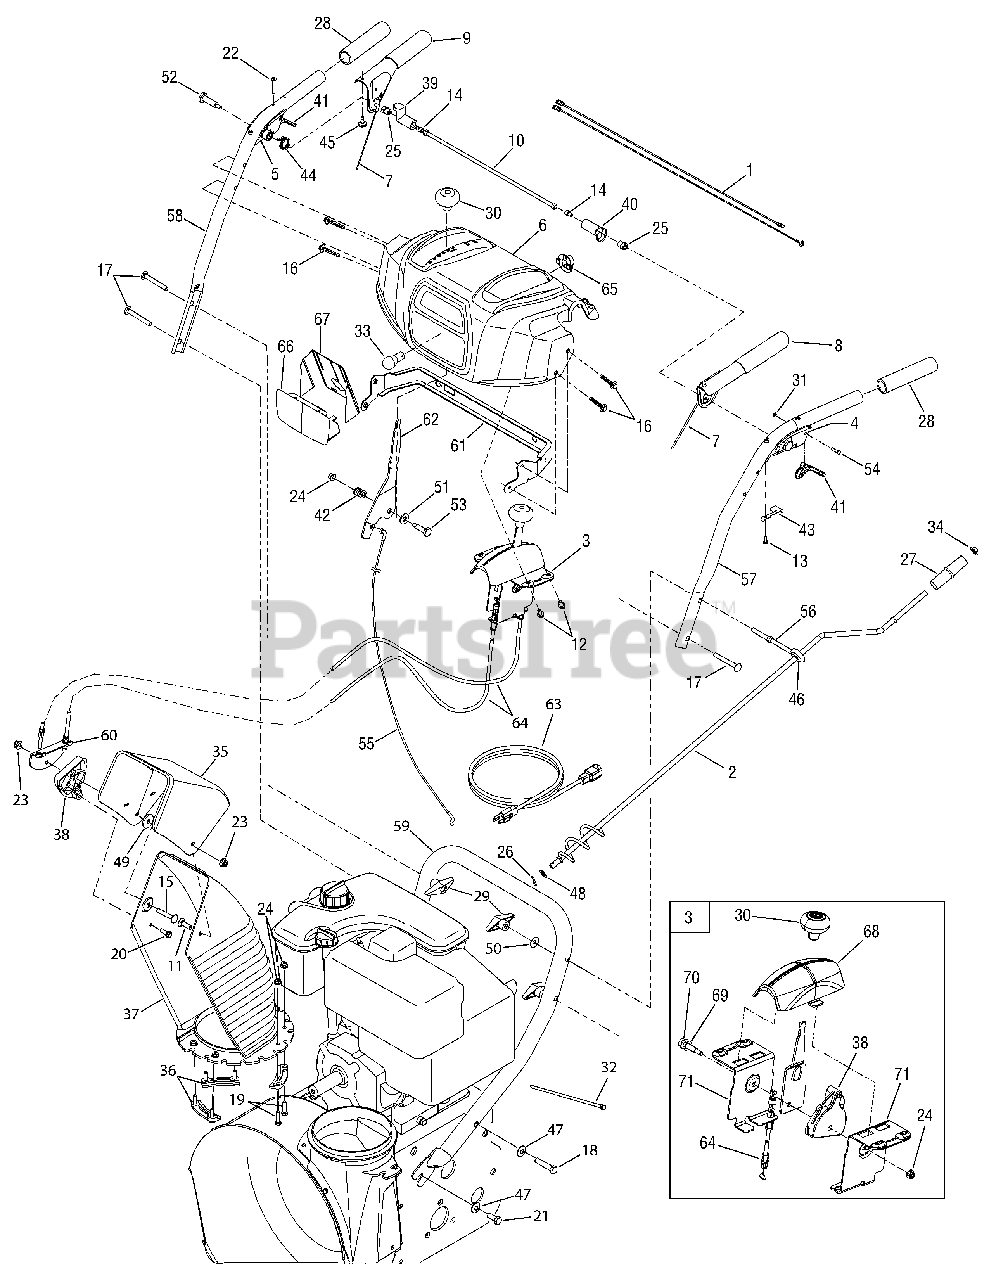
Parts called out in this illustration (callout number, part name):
1	Wire Harness
3	2-Way Chute Control (TM) Assy
4	Handle Clutch Lock - LH
5	Handle Clutch Lock - RH
6	Handle Panel
7	Cable Assembly, Auger/Drive
8	Handle Engage Assy - LH
9	Handle Engage Assy - RH
10	Rod Ass’y, Clutch Lock Pivot
11	Screw, Carriage, 5/16-18 x 1.0
12	Hi-Lo Screw, 1/4-15 x 0.5
13	Screw, #8-16 x 0.50
14	Screw, 1/4-20 x.375
15	Bolt, Carriage, 5/16-18 x 1.75
16	Screw, 1/4-20 x 1.625
17	Screw, Carriage, 5/16-18 x 2.5
18	Screw, Hex, 3/8-16 x 2.00 Lock, Gr5
19	Screw, 1/4-20 x 1.00
20	Hi-Lo Screw, 1/4-15 x .75
21	Screw, Hex, 3/8-16 x 1.0 Lock, Gr5
22	Screw, #10-24 x 0.375
23	Flange Lock Nut, 5/16-18
24	Flange Lock Nut, 1/4-20
25	Shoulder Nut, 1/4-20
26	Pin, Internal Cotter Pin
27	Knob, Crank
28	Handle Grip
29	Knob, Wing Nut, 5/16-18
30	Shift Knob
31	Ring, Retainer
32	Cable Tie
33	Lamp
34	Cap, Push, 3/8
35	Upper Chute
36	Chute, Flange Keeper
37	Lower Chute
38	Chute Tilt Cable Guide
39	Lock Plate
40	Clutch Lock Cam
41	Steering Control
42	Compression Spring
43	Clutch Lock Spring
44	Torsion Spring
45	Rubber Bumper
46	Grommet, Rubber
47	Washer, Bel, .375 x .87 x .063
48	Washer, .375 x .738 x .063
49	Flat Washer
50	Washer, Belleville, .34 x .872 x .06
51	Flat Washer
52	Shoulder Screw, 1/4-20 x 1.345
53	Shoulder Screw
55	Speed Selector Cable
63	Extension Cord, 110V
64	Cable, Chute Tilt
65	Light Socket
67	Reflector Label
68	Cover, Tilt Cover
69	Washer, Spring, .39 x .625 x .012
70	Screw, Shoulder, .31 x .995:1/4-20
